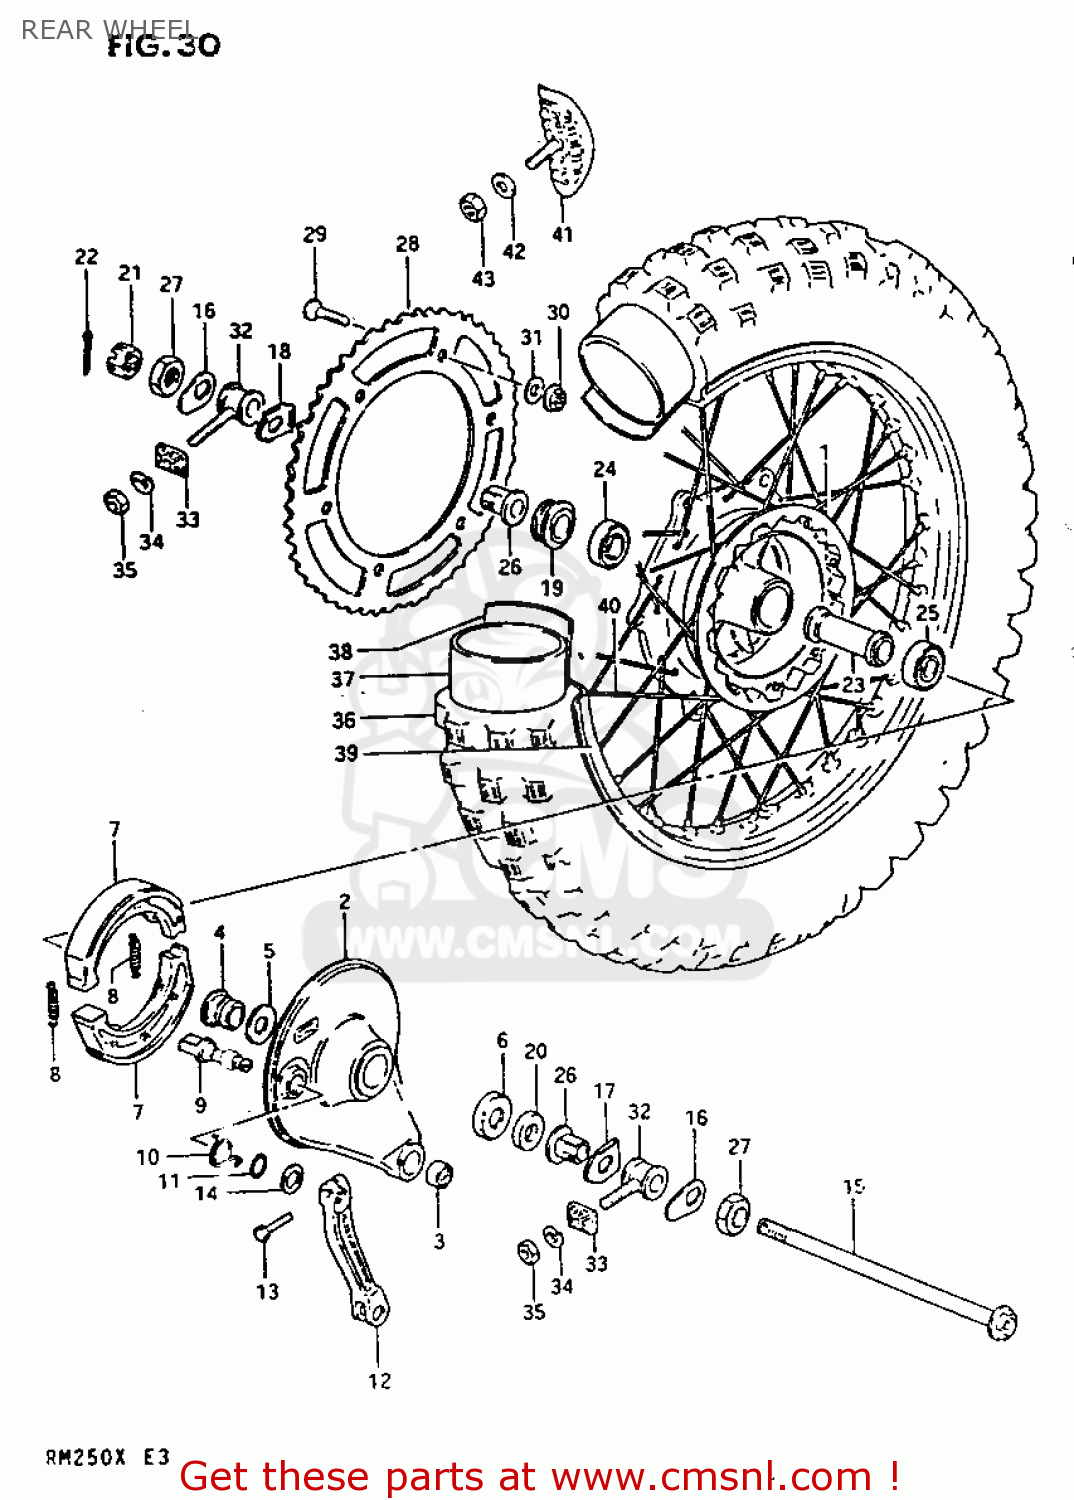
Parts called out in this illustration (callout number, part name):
1	DRUM,REAR HUB
2	PANEL SET,REAR HUB
3	SPHERICAL BRNG,TORQUE LINK
4	SPACER,RR BRAKE ANCHOR PANEL
5	SEAL,OIL(20X27X5)
6	CVR,RR BRAKE AHR PNL DUST SEAL
7	SHOE,BRAKE (MCA)
8	SPRING(L:35.8)
9	CAM,FR BRAKE
10	SPRING
11	O RING(D:2.5,ID:11.4)
12	LEVER,RR BRAKE CAM
13	BOLT
14	WASHER(12.5X20X1)
15	AXLE,REAR
16	WASHER,CHAIN ADJUST GUIDE
17	PLATE,CHAIN ADJUSTER,RIGHT
18	PLATE,CHAIN ADJUSTER,LEFT
19	SPACER,RR AXLE,L
20	SPACER,REAR AXLE,RIGHT
21	NUT
22	COTTER PIN
23	SPACER
24	BEARING
25	BEARING
26	SPACER,CHAIN ADJUSTER
27	NUT
28	SPROCKET,REAR
29	SCREW(8X33.5)
30	NUT
31	WASHER
32	ADJUSTER,CHAIN
33	PLATE,CHAIN ADJUSTER GEAR
34	WASHER,LOCK,10
35	NUT
36	TIRE
37	TUBE,INNER
38	PROTECTOR,WHEEL,INNER
39	RIM,REAR WHEEL (2.15-18)(
40	SPOKE SET,REAR
41	STOPPER,BEAD
42	WASHER
43	NUT
